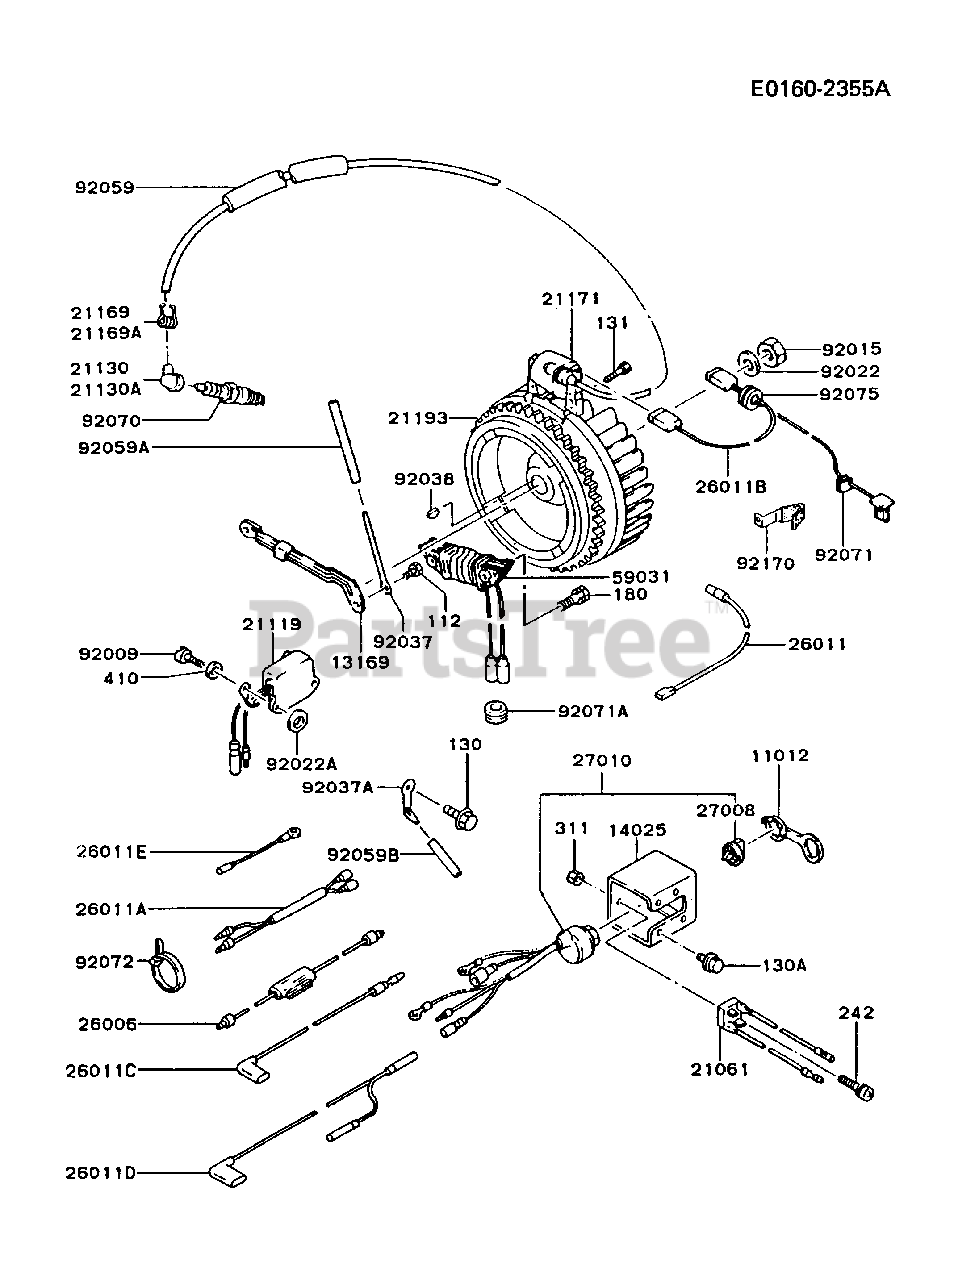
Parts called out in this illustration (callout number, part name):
112	BOLT-UPSET
130	BOLT-FLANGED
130A	BOLT-FLANGED
131	BOLT-FLANGED
180	BOLT-UPSET-WS
242	SCREW-PAN-WSP+-
311	NUT-HEX
410	W-PLAIN-S
